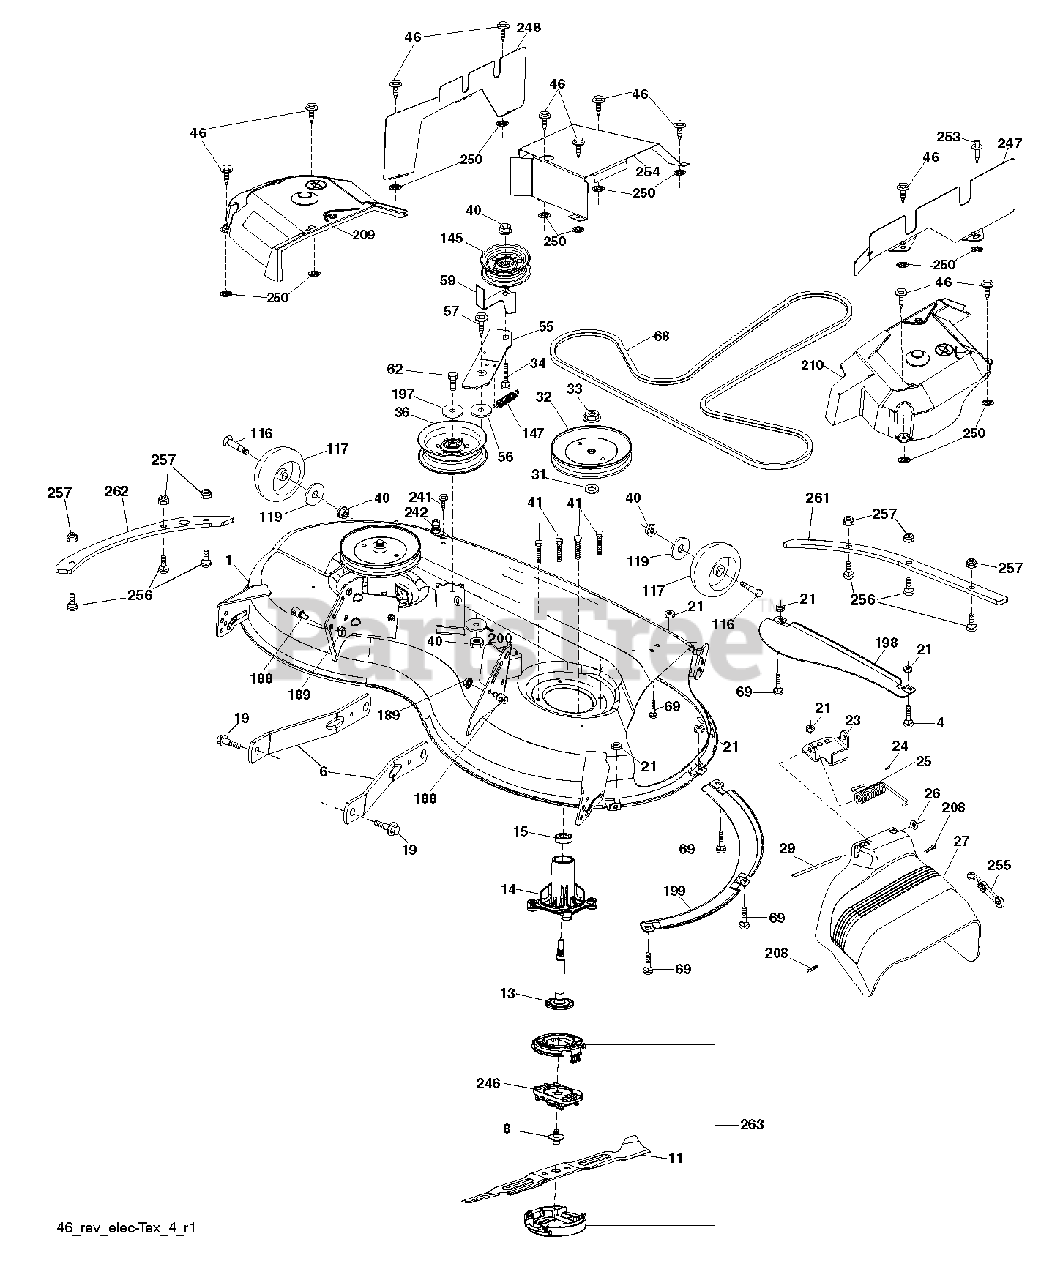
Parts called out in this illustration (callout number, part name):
1	DECK SVC 46"417585X668
4	BOLT
6	ARM.SUSPENSION.MOWER.R
8	SCREW.SEMS.7/16-20X1.HEX.HEAD
11	BLADE.REVOLTION.46"BAGER.PT43
13	SHAFT ASM.REV.TALL.N/GREASEBL
14	HOUSING.MANDREL.REV.TALL.N/GRS
19	BOLT.SHOULDER
21	LOCKNUT
23	BRKT.DEFLECTOR.38"2005+
24	CAP-SLEEVE LT
25	SPRING.TORSION.DEFLECT
26	NUT PUSH M
27	SHIELD SUBASM DEFLECTOR 46 FRE
29	ROD.HINGE
31	WASHER.SPACER.MANDREL
32	PULLEY.MANDREL.5.438.PD
33	NUT.FLANGE.LOCK.TOP
34	BOLT.3/8-16X1.50
36	PULLEY.IDLER.2006
40	NUT LOCK FLG 3/8-16 UNC
41	BOLT.HEX.WASHR.HED.313-18X1.19
46	SCREW.1/4-20X5/8
56	SPACER.RETAINER
57	SCREW 3/8-16X1
59	GUARD, BELT
62	BOLT-HEX EAK
68	V-BELT
69	BOLT
116	BOLT.SHOULDER.3/8-16X3-5/8.
117	WHEEL. GUAGE RALLY
119	WASHER
145	PULLEY.IDLER.48"PRIMARY
147	SPRING.MOWER.DRIVE.ELECTRIC
188	STUD.FASTNER.W/ANTI-ROTATE
189	NUT LOCK HEX FLANGE 5/16-18
197	WASHER
198	BAFFLE CENTER FRONT
199	BAFFLE FRONT RH
200	WASHER.13/32 X 1 X 1/2.11GUARD
208	SCREW 3/8-16X1/2
210	Mandrel Cover, RH 46" Deck Tex French
241	SCREW.TT.#10-32X.5.3/8.FLANGE
242	PORT.WASHOUT
246	HOLDER.BLADE.REVOLUTION
247	SHIELD RIGHT
248	SHIELD LEFT
250	PALNUT 1/4
253	SCREW
254	SHIELD REAR
255	ELASTIC STRAP KIT
256	SCREW.BUTTONHEAD.1/4-20X1
257	NUT T
261	PLATE.RNFRCMENT.46.FRONT X431
262	PLATE.RFORCRMRNT.46.SIDE X431
263	CAP.REVOLUTION ASM
